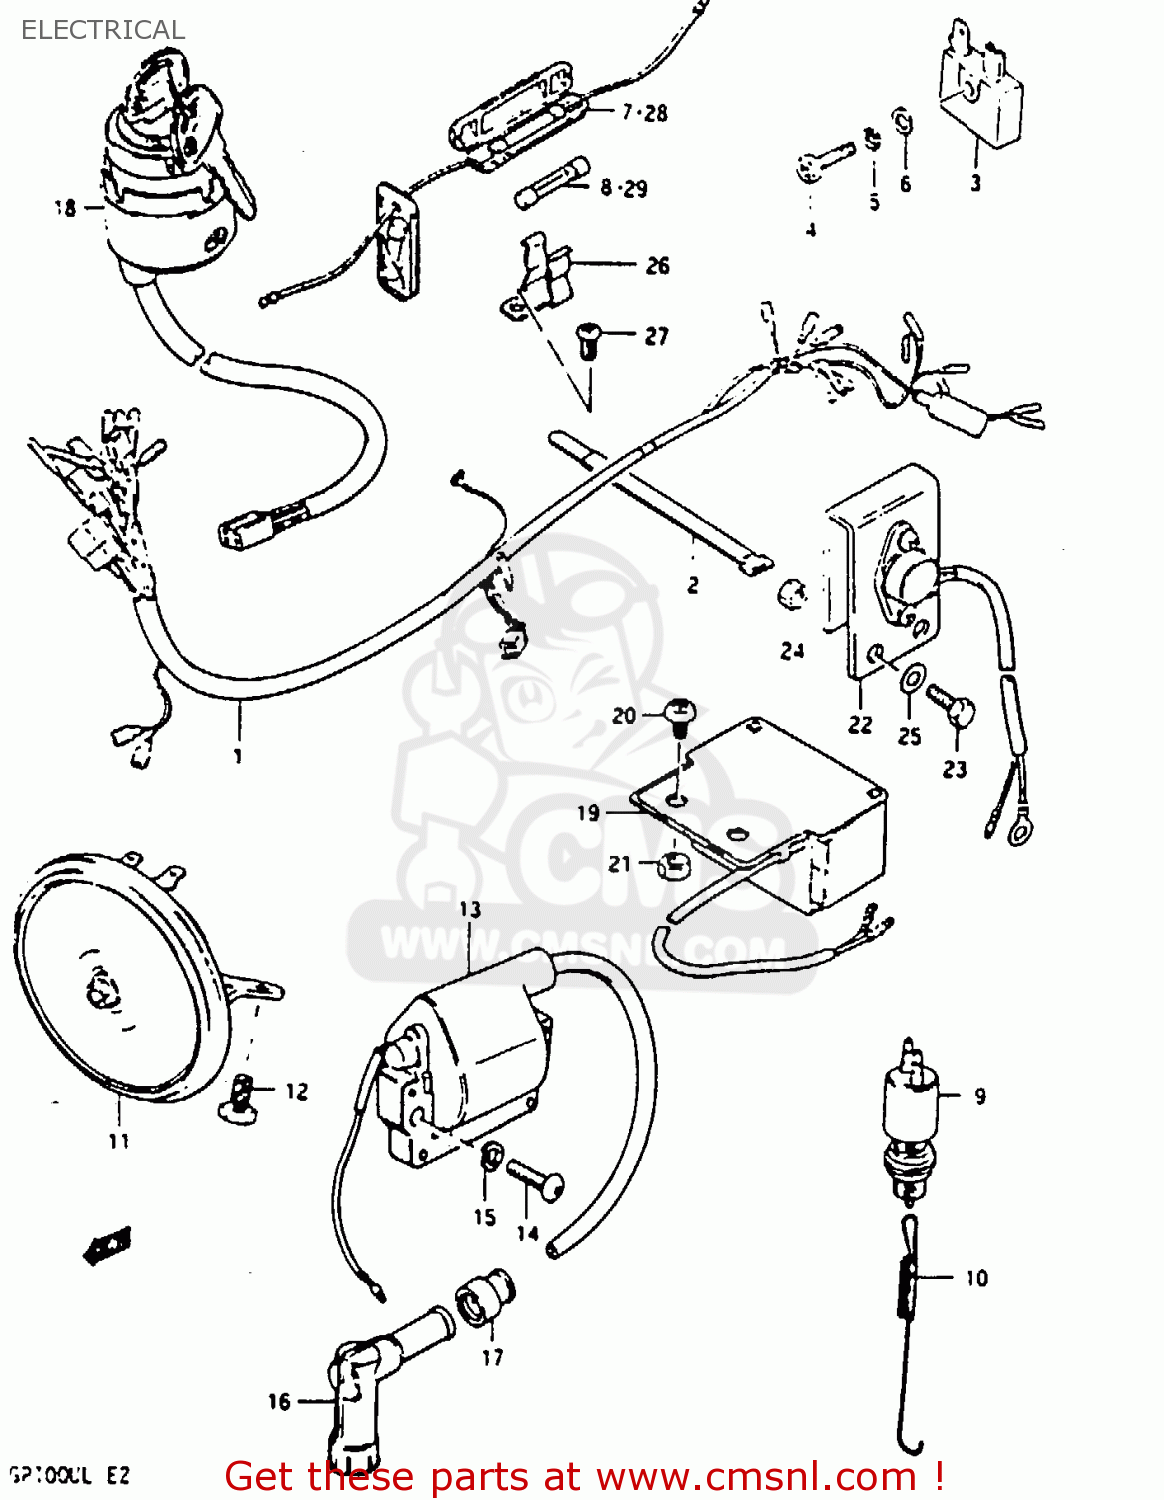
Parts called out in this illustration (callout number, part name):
1	WIRING HARNESS
2	CLAMP
3	RECTIFIER ASSEMBLY
4	SCREW(5X18)
5	LOCK WASHER
6	WASHER
7	CASE ASSY,FUSE
8	FUSE(10A)
9	SWITCH ASSY,BRAKE LAMP
10	SPRING
11	HORN ASSY
12	BOLT
13	COIL ASSEMBLY,IGNITION
14	SCREW 5X20
15	WASHER
16	CAP,SPARK PLUG
17	SEAL, HIGHTENSION CORD
18	SWITCH ASSY,IGNITION
19	RESISTOR ASSY
20	SCREW
21	NUT 6MM
22	REGULATOR ASSEMBLY
23	BOLT
24	NUT 6MM
25	WASHER
26	HOLDER,FUSE CASE
27	SCREW,6X6
28	FUSE CASE, REGULATOR
29	FUSE(5A)
